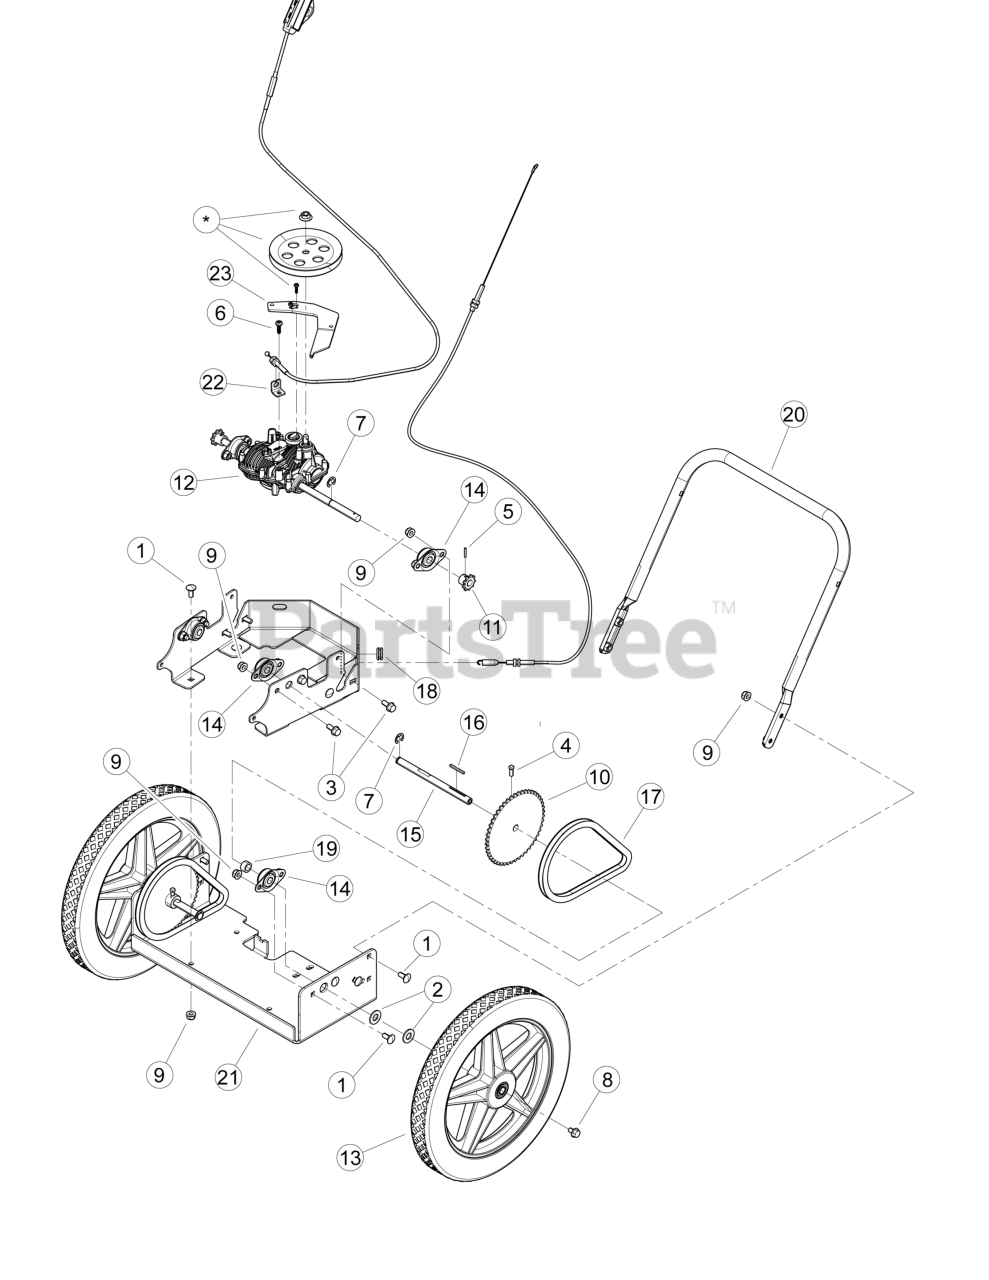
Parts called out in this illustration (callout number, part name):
1	BOLT, 5/16-18 × 3/4 SN GR5 CRG
2	WASHER, 1/2 SAE FLAT
3	BOLT, 5/16 × 3/4 FLANGE NC
4	SCREW, SET 1/4 × 5/8 SQ HD
5	PIN, 1/8 × 3/4 IN. SPRING LOCK
6	SCREW, M6 × 1 mm × 20 mm FORMING
7	CLIP, 1/2" E
8	BOLT, 5/16-18 × 1/2 G5 HH SERRATED FLANGE
9	NUT, 5/16-18 NYLOCK FLANGE
10	SPROCKET, 35B48T WITH .500 HUB ID
11	SPROCKET, 35B9T WITH .500 HUB ID
12	TRANSMISSION, 3 SPEED MG512
13	WHEEL, TRIMMER HUB 15 × 1.75
14	BUSHING, FLANGE 1/2 DIA 38 DEG MAX ANGLE
15	SHAFT, WT AXLE
16	KEY, 1/8 × 1/8 × 1-3/8
17	CHAIN, #35 × 60 PITCH W/ C LINK
18	GROMMET, 3/8 ID PUSH IN
19	SPACER, .75 OD × .5 ID × .37
20	HANDLE BAR, LOWER TRIMMER PAINTED
21	BRACKET, WT BASE
22	BRACKET, TRANS SPEED CABLE
23	LEVER, WT TRANS ENGAGE SS
